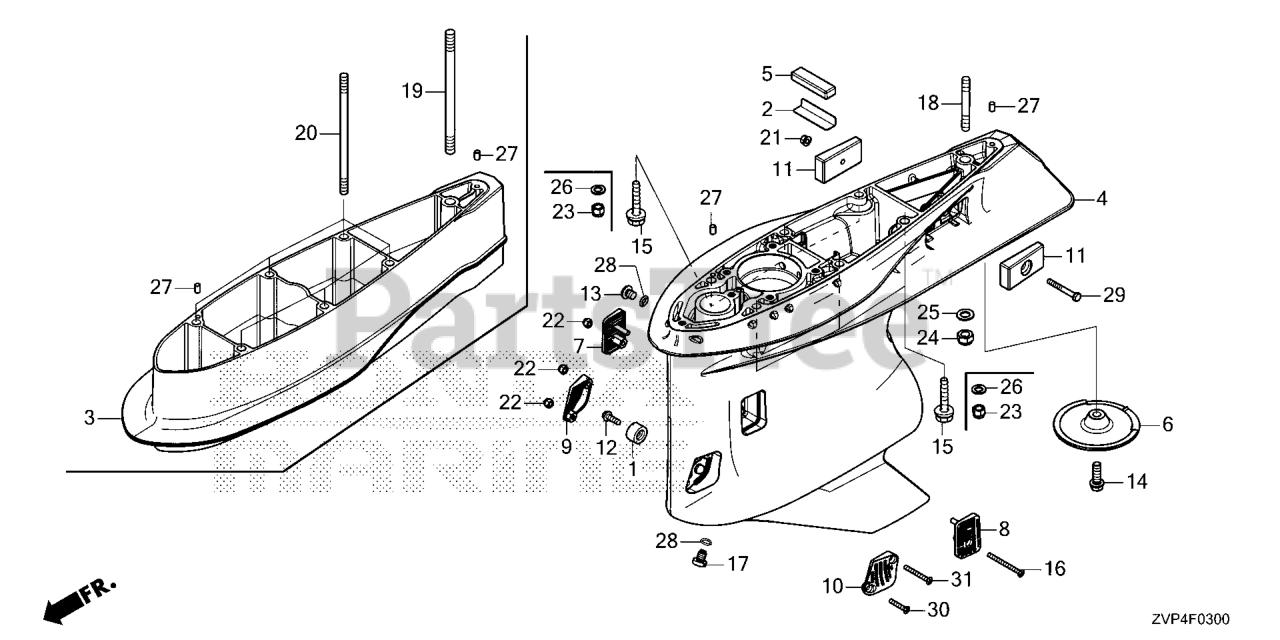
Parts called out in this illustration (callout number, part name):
1	METAL, ANODE
2	PLATE, RUBBER SETTING
3	SEPARATOR *NH565*
3	SEPARATOR *NHB14M*
4	CASE, GEAR *NH565*
4	CASE, GEAR *NHB14M*
5	GROMMET, GEAR CASE
6	COVER, GEAR CASE *NHB14M* (AQUA MARINE SILVER METALLIC)
6	COVER, GEAR CASE *NH565* (GRAND PRIX WHITE)
7	SCREEN, RR. R WATER
8	SCREEN, RR. L WATER
9	SCREEN, FR. R WATER
10	SCREEN, FR. L WATER
11	METAL, ANODE
12	BOLT, FLANGE (6X18)
13	BOLT, OIL CHECK
14	BOLT-WASHER (10X32)
16	SCREW, OVAL (5X60)
17	BOLT, DRAIN PLUG
19	BOLT, STUD (12X170)
20	BOLT, STUD (10X170)
21	NUT, SELF-LOCK (6MM)
22	NUT, SELF-LOCK (5MM)
23	NUT, SELF-LOCK (10MM)
24	NUT, SELF-LOCK (12MM)
25	WASHER, PLAIN (12MM)
26	WASHER, PLAIN (10MM)
27	PIN, DOWEL (6X10)
28	O-RING (6.9X1.45)
29	BOLT, HEX. (6X50)
30	SCREW, OVAL (5X30)
31	SCREW, OVAL (5X45)
